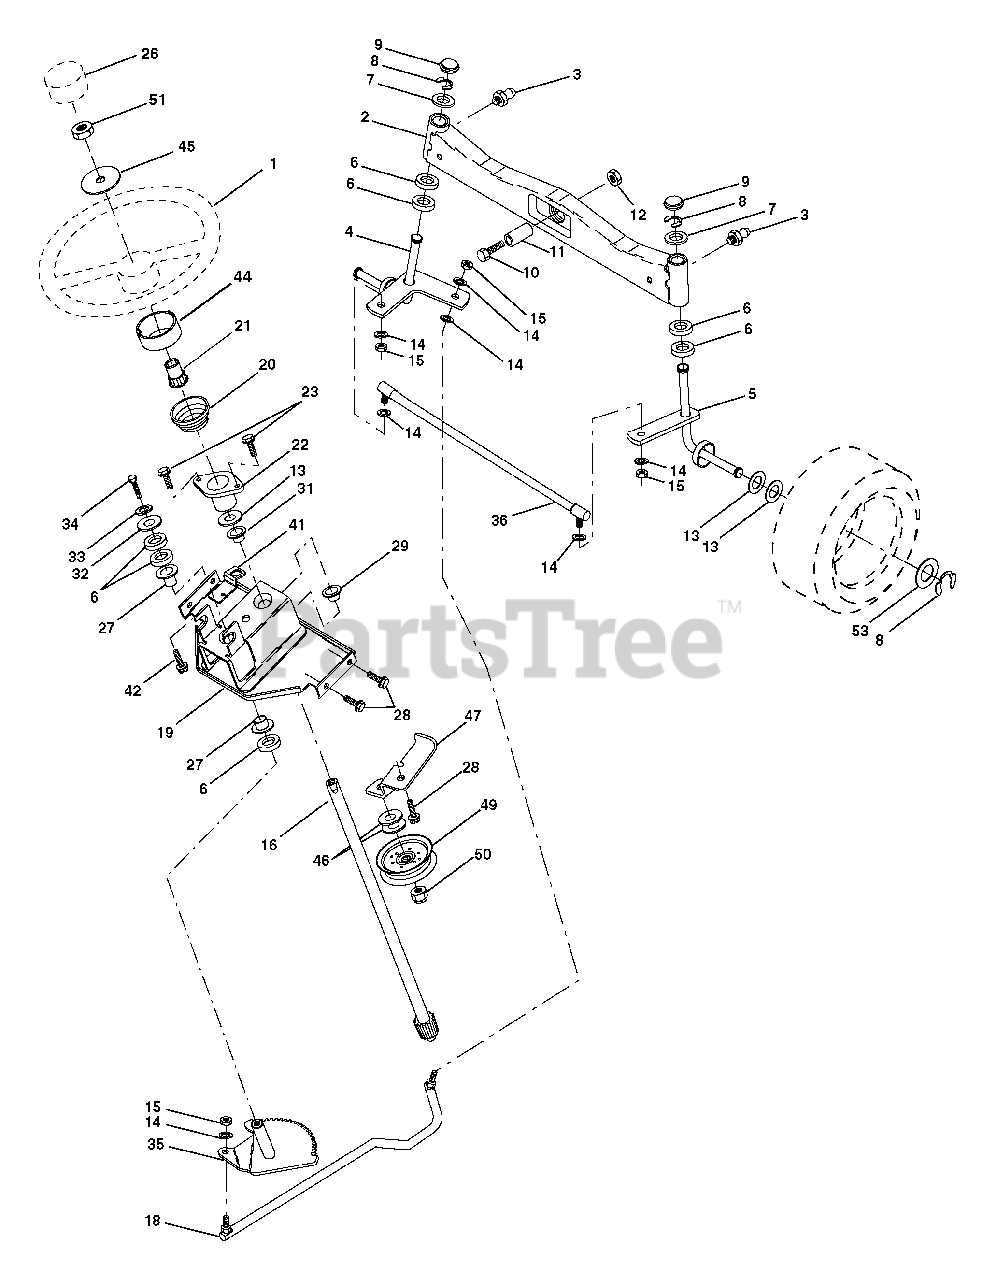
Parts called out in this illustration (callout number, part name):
1	Wheel, Steering
2	Axle Asm., Front
3	Fitting, Grease
4	Spindle Asm, LH
5	Spindle Asm., RH
6	Bearing, Race Thrust Harden
7	Washer 25/32 x 1-5/8 x 16 Ga.
8	Ring, Klip #T5304-75
9	Cap, Spindle
10	Bolt, Fin Hex 5/8-11 x 2-3/4
11	Spacer, Brg. Axle Front
12	Nut, Lock Flange 5/8-11 unc
13	Washer 25/32 x 1-1/4 x 16 Ga.
14	Washer, Lock Hvy Hlcl Spr 3/8
15	Nut Lock Center 3/8-24 unf
16	Shaft Asm., Steering
18	Draglink, Ball Joint Solid Vgt
19	Support Asm., Steering Vgt
20	Boot Steering Stealth
21	Adapter, Wheel Steering
22	Bushing, Strg.
23	Screw
26	Insert Cap Strg WH
27	Bearing, Col. Strg.
28	Screw Hexwsh thdr 3/8-16 x 3/4
29	Bearing, Flange
31	Bushing, Nyliner Snap
32	Washer 11/32 x 1 x 10 Ga.
33	Washer, Lock Hvy Hlcl Spr 5/16
34	Bolt, Hex Hd 5/16-18 x 3/4
35	Gear, Sector Steering
36	Tie Rod
41	Bracket Switch Interlock Vgt 97
42	Screw Thdrol 5/16-18 x 1/2 Tyt
44	Extension Steering
45	Washer 9/16 ID x 2-3/8 OD 12 Ga.
46	Washer 13/32 x 1 x 10 Ga.
47	Bracket Asm. Idler Stationary
48	Screw 3/8-16 x .75
49	Pulley Idler Flat
50	Nut Lock Flg. 3/8-16 unc
51	Nut Hex Jam Toplock 1/2-20 unf
53	Washer Harden .793 x 1.637 x .060
